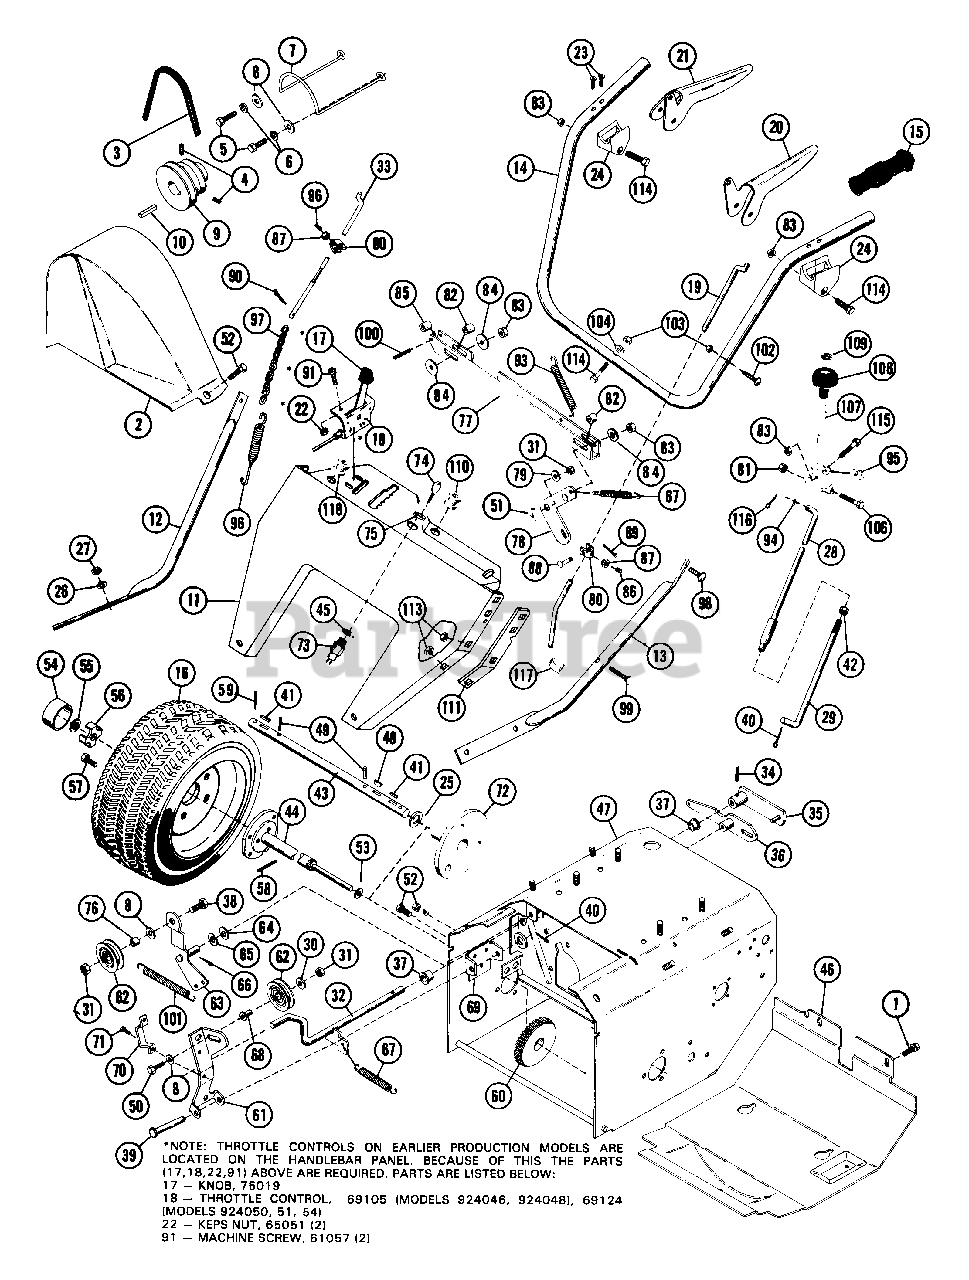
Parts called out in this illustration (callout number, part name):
1	BLT-SERHFWH .31-18X.50 PL
2	BELT COVER
3	BELT,3L 33.00 RAW LAM C-L2089
3	V-BELT, 3L-RAW EDGE
4	SCR-SET .32-18X.38 SKHCUPNL OH
5	TIE DOWN
6	WSHR-LK-EXT .313X.030 PL
7	BELT FINGER
8	WSHR-FL-STL .38X.875X.083 PL
9	ENGINE SHEAVE
9	SHEAVE, ENGINE
10	KEY-STR .25X1.75X.25
11	HANDLEBAR PANEL
12	LOWER HANDLEBAR RH
13	LOWER HANDLEBAR LH
14	UPPER HANDLEBAR SW
14	UPPER HANDLEBAR LW
15	GRIP
16	TIRE & WHEEL ASSEMBLY CARLISLE
16	TIRE 4.10/3.50X6
16	TUBE
16	WHL 6 IN O.D.
16	WHEEL ASSEMBLY
16	TIRE
16	WHL
16	TERRA TIRE & WHEEL ASSEMBLY
16	TIRE 16X6.50-8 2 PLY
19	CLUTCH ROD
20	TRACTION CLUTCH HANDLE WITH DE
21	ATTACHMENT CLUTCH HANDLE
23	SCR-TAP 12-14X1.50 CROVH PL BT
24	HANDLE PIVOT
25	WSHR-FL-STL .755X1.375X.125
26	WSHR-LK .375X.115 HVY PL
27	NUT-HEX .375-16
28	UPPER SHIFT ROD
29	LOWER SHIFT ROD
30	WSHR-FL-STL.312X.734X.065PL
31	NUT-LK .312-18 GR A PL
32	ACTIVATING SHAFT
33	ATTACH CLUTCH ROD
34	PIN-ROLL .156X.88
35	LEVER CLUTCH
37	BSHG-FLG.500X.625X.312X.750NY
38	BLT-HEX .31-18X1.00 PL GR 2
39	PIN-CLEV .309X2.25
40	PIN-COTR .09X.75 PL
41	KEY-FTHR .188X1.25X.187 SAE
42	NUT-HEX .312-24 PL
43	AXLE SHAFT
44	R H AXLE SHAFT
44	R H AXLE
45	WSHR-LK-INT .625X.045 PL
46	BOTTOM COVER
47	FRAME
48	KEY-WDRF .25X.750X.313 SAE91
49	PIN-ROLL .188X1.25
50	BLT-HEX .31-18X1.25 PL GR2
51	SPACER BUSHING .5 X .32 X .163
52	BLT-SERHFWH .25-20X.50 PL
53	WSHR-FL-STL .880X1.380X.062
53	WSHR-FL-STL .505X.750X.015
54	HUB CAP
55	PUSHNUT
56	SPINDLE CUP
57	BLT-WHL .50-20X.75 GR5 PL
58	PIN-ROLL .188X1.25
58	PIN-ROLL .188X1.50
59	PIN-COTR .12 X 1.25 PL
60	DIFFERENTIAL ASSEMBLY
60	SPUR GEAR, FELLOWS 35T .750 ID
61	ARM, IDLER
62	IDLER
63	IDLER ARM
64	WSHR-FL-STL .382X.812X.023 PL
65	WAVE WASHER .406X.750X.063FH
66	PIN-COTR .12X1.0 PL
67	SG-TENS .062X.43X5.75 WLD 20
68	SPCR, BRG .315X.50X.688X.281
69	BRACKET
70	RETURN CLIP
71	SCR-TAP 10-24X.375 HWH PL TR
72	WHEEL HUB
73	SWITCH & KEY SET ASSEMBLY
74	KEYS
75	NUT .625-32 ALUM
76	SPACER .50 X .32 X .42
78	BELLCRANK
79	WSHR-FL-STL .328X.875X.062 PL
81	NUT-LK .312-18 GR A PL
82	BSHG-SLV .250X.375X.640
83	NUT-LK-CTR .250-20 PL
84	WSHR-FL-STL .281X1.250X.048PL
85	BSHG-SLV .188X.500X.480
86	SCR-SET .25-20X.75 SKHCUP OH
87	NUT-HEX JAM .25-20 YWZC
88	CLEVIS PIN
89	PIN-HAIR INT .06X.18X.77
90	PIN-COTR .12X.50 PL
93	SG-TENS .035X.45X2.75 WLD 3.5
95	SG-TENS .125X.50X1.38
96	SG-TENS .091X.56X6.12 WLD 40
97	CLUTCH CHAIN
98	BLT-RDHDSQNK .31-18X.75 PL BL
99	BLT-RDHDSQNK .31-18X1.50 PL BL
100	PIN-ROLL .188X.88
101	SG-TENS .080X.73X3.06 WLD 20
102	BLT-RDHDSQNK .25-20X1.50 PL BL
103	NUT-LK-FLG .250-20 PL
104	WSHR-FL-STL .265X.500X.087 PL
106	BLT-HEX .31-18X2.50 PL GR2
107	ROD
109	RG-RTNG-EXT .500X.015
110	SNAP BUSHING
111	L H STIFFENER
113	NUT-FLG. .312-18 PL
114	BLT-HEX .25-20X1.50 PL GR5
115	BLT-HEX .25-20X1.00 GR2
116	PIN-COTR .12X.75 PL
118	SNAP BUSHING-.437
